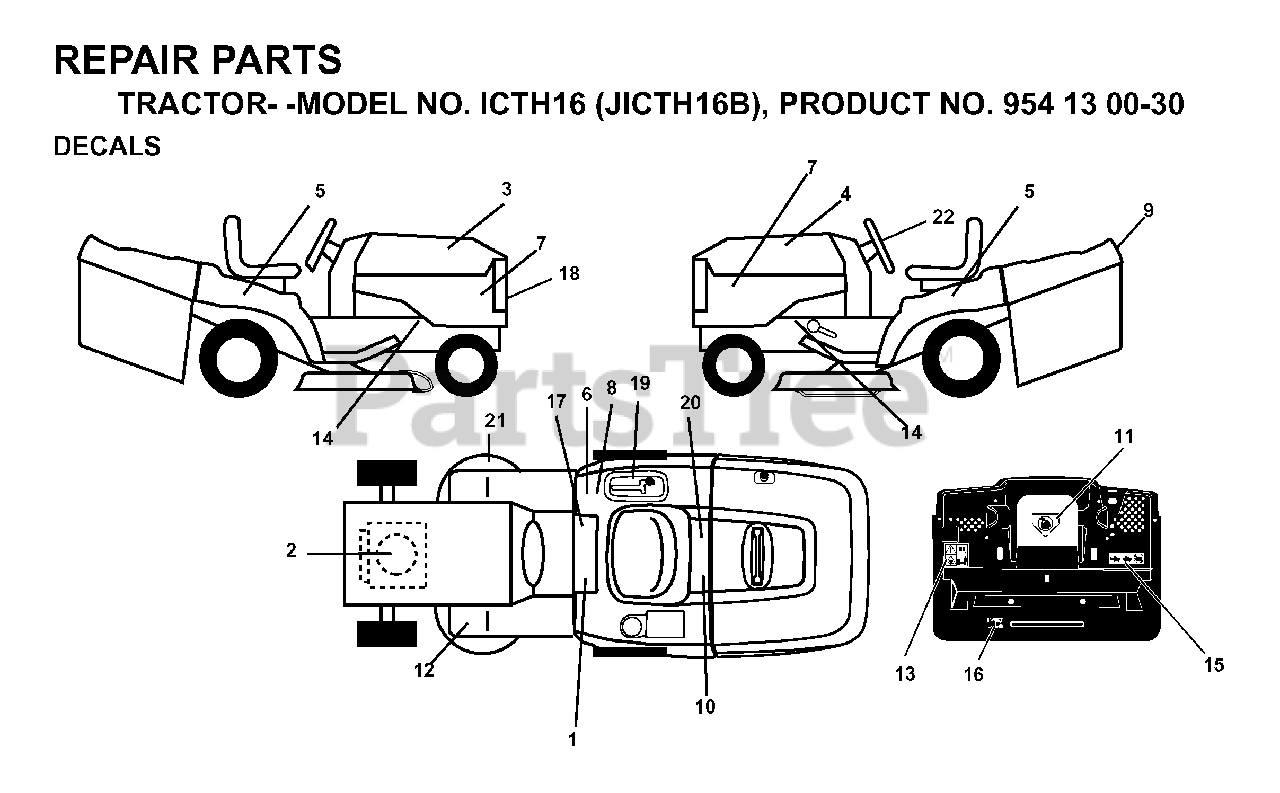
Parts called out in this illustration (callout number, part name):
1	DECAL READ OWNER'S MAN SYMS
6	DECAL CERTIFICATION
8	DECAL EUROPE STANDARD CE
10	DECAL BTRY SYMBOLS
11	DECAL MOWER CUT/FINGER
17	DECAL PARK BRAKE
20	DECAL.BYPASS.FENDER.CRD.LT.YT
21	DECAL
